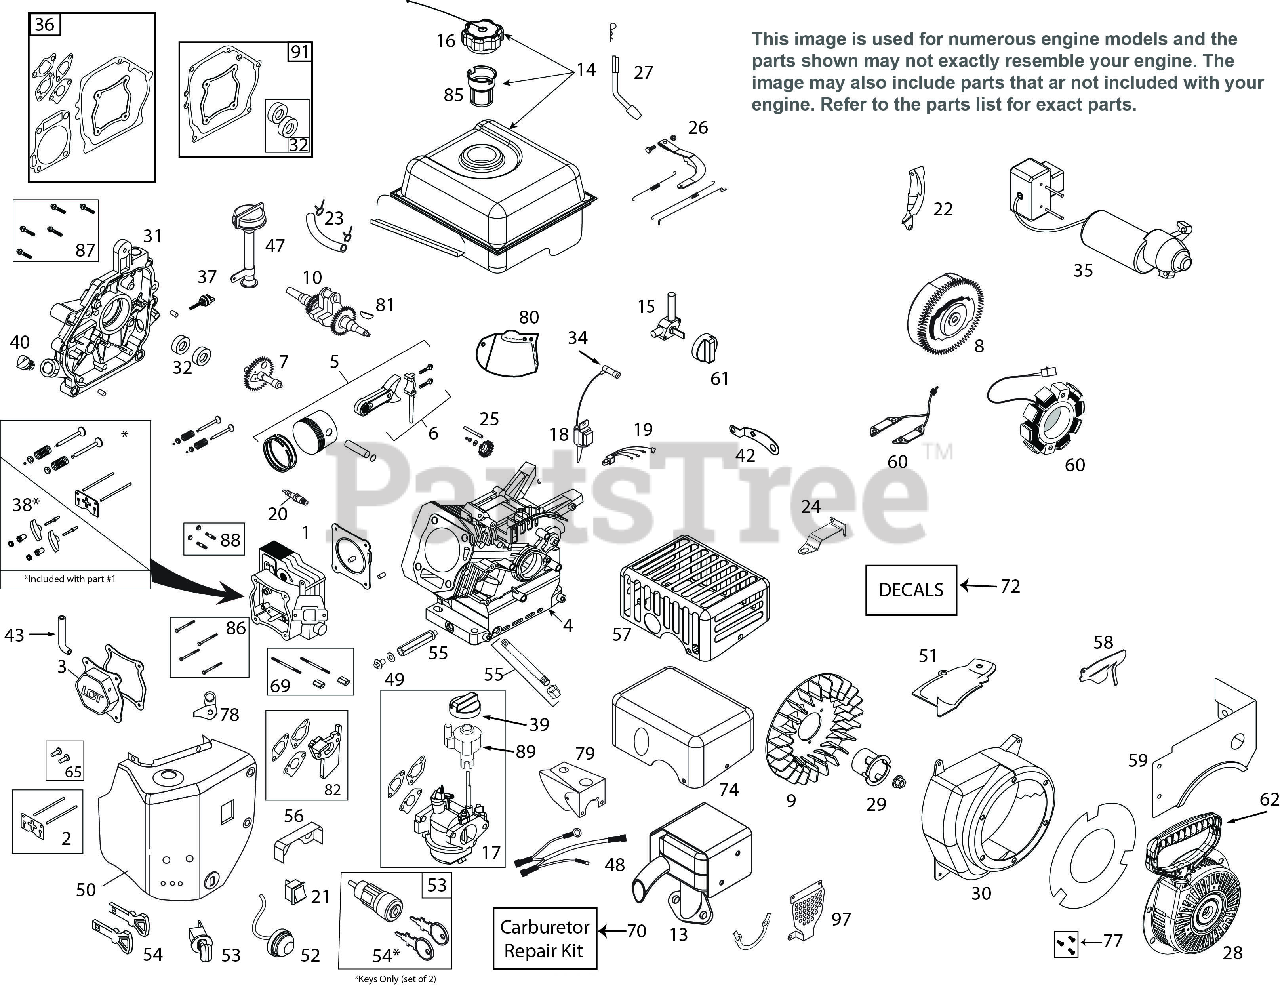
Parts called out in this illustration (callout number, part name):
1	CYLINDER HEAD ASSY (W/GASKET)
2	PUSH ROD & PLATE KIT (W/GASKT)
3	VALVE COVER (W/GASKET)
3	VALVE COVER, "KING OF SNOW"
5	PISTON & ROD ASSEMBLY
7	CAMSHAFT - MCR
8	FLYWHEEL - ELECTRIC START
9	COOLING FAN - FLYWHEEL
10	CRANKSHAFT (#18 KEYED)
13	MUFFLER ASSEMBLY
14	FUEL TANK ASSY
15	FUEL TANK ON/OFF VALVE
16	CAP, FUEL TANK BLACK
17	CARBURETOR (W/GASKETS)
18	IGNITION COIL (CDI) (STANDARD)
20	SPARK PLUG, ARIENS AX
22	SHIELD - FLYWHEEL (ELECTRIC)
23	FUEL HOSE KIT 1/4-230MMW/CLMPS
24	SPEED CONTROL BRACKET (FIXED)
25	GOVERNOR GEAR ASSEMBLY
26	GOVERNOR ARM & LNK KIT 3600RPM
27	GOVERNOR ARM PADDLE
28	RECOIL STARTER ASSY RND-BLACK
29	STARTER CUP RND STYLE STARTER
30	BLOWER HOUSING (MATTE BLACK)
31	CRANKCASE COVER ASSY W/GASKET
32	OIL SEAL KIT(2 PCS 3/4" CRANK)
34	SPARK PLUG BOOT (W/MTL SHIELD)
35	120V ELECTRIC STARTER
36	ENGINE GASKET KIT
37	SMALL BLACK OIL DIPSTICK
38	ROCKER ARM KIT (W/GASKET)
39	CHOKE CONTROL KNOB (RED)
39	CHOKE ON/OFF KNOB (BLACK)
40	NON-REMOVABLE PLASTIC PLUG
43	BREATHER TUBE
47	HIGH OIL-FILL TUBE/DIPSTICK
48	WIRE HARNESS, W/O ON/OFF SWITCH
49	OIL DRAIN PLUG (W/WASHER)
50	HEATER BOX, W/O ON/OFF SWITCH
51	SHIELD - CYLINDER
52	PRIMER BULB WITH HOSE-SNOW (RED)
52	PRIMER BULB WITH HOSE (BLACK)
53	SAFETY KEY SWITCH (W/KEYS) (RED)
53	PUSH/PULL KEY & SWITCH (BLACK)
54	KEY, PUSH/PULL LCT (2/PACKAGE)
54	PUSH/PULL KEY (BLACK)
55	FRONT OIL DRN PIPE & NUT ASSY
57	CE COMPLIANT MUFFLER SHIELD
58	GOV AND CARB SHIELD, COMPOSITE
59	FUEL TANK SKIRT
61	FUEL CONTROL KNOB (RED)
61	FUEL ON/OFF KNOB (BLACK)
65	TAPPET KIT (SET OF 2)
69	CARBURETOR STUDS & COUPLNG KIT
70	CARBURETOR REPAIR KIT
72	SNOW LABEL KIT
74	MUFFLER HEAT SHIELD COVER
77	RECOIL BOLT KIT
78	BREATHER TUBE BRACKET
81	WOODRUFF FLYWHEEL KEY 5-PACK
82	CARBURETOR SPACER
85	FUEL TANK STRAINER
86	HEAD BLT KIT 136-179-208-254CC
87	CC COVER BLT KIT 179-208-254CC
88	MUFFLER MTG STUD KIT
91	CRANKCASE GASKET KIT 208GEN1&2
97	MUFFLER MANIFOLD SHIELD
9999	HIGH ALT JET-208CC L10-1 CARB
9999	HARDWARE KIT (4 M6X10 FLG BLT)
9999	STARTER SWITCH SCREWS
